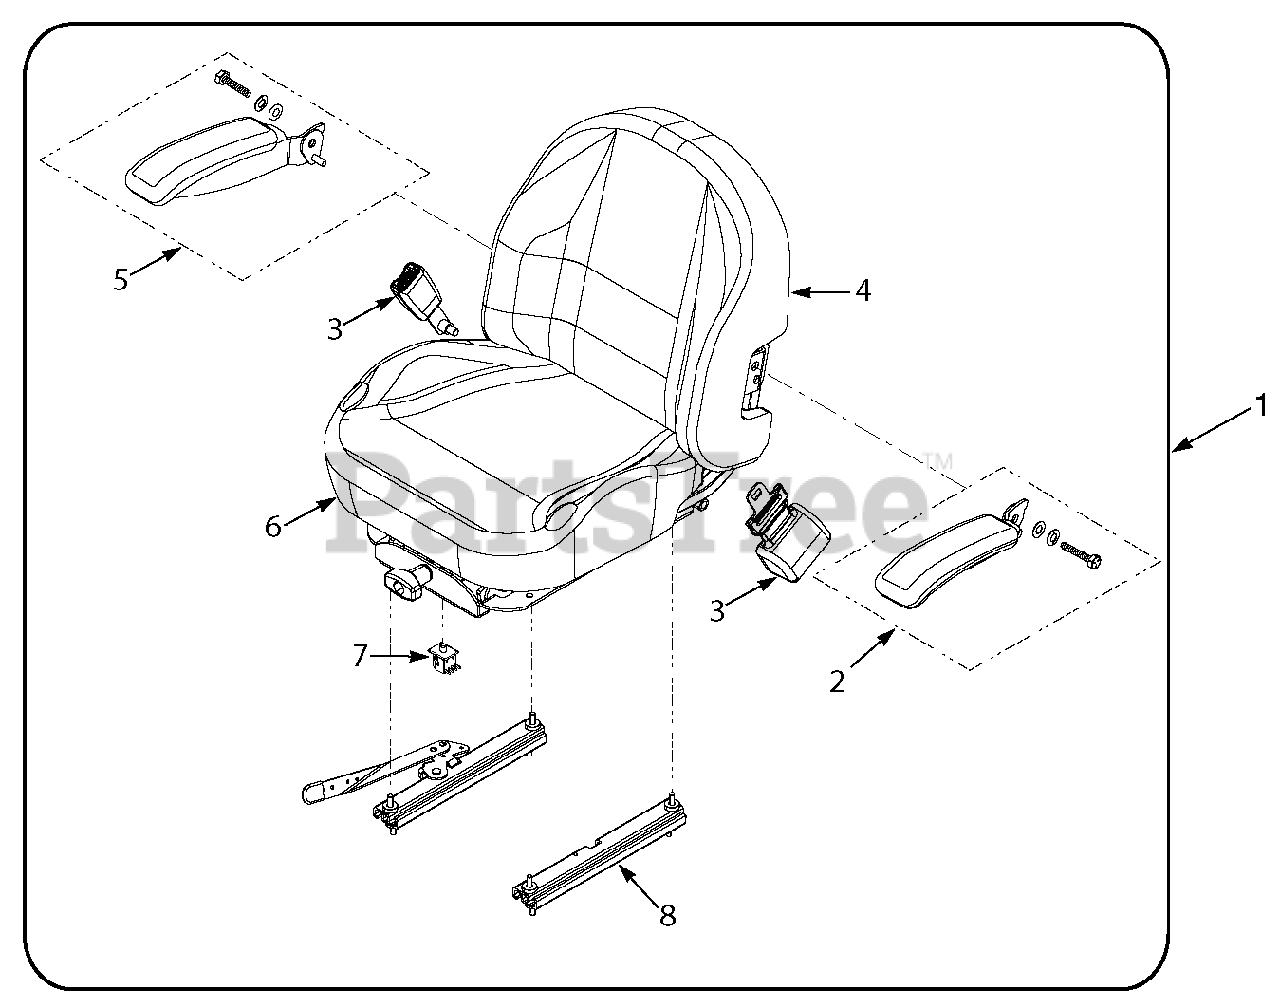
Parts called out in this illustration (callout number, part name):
1	Seat Assembly
2	Armrest Kit, LH
3	Seatbelt Kit
4	Back Cover
5	Armrest Kit, RH
6	Cushion Cover
7	Switch
8	Track Set
